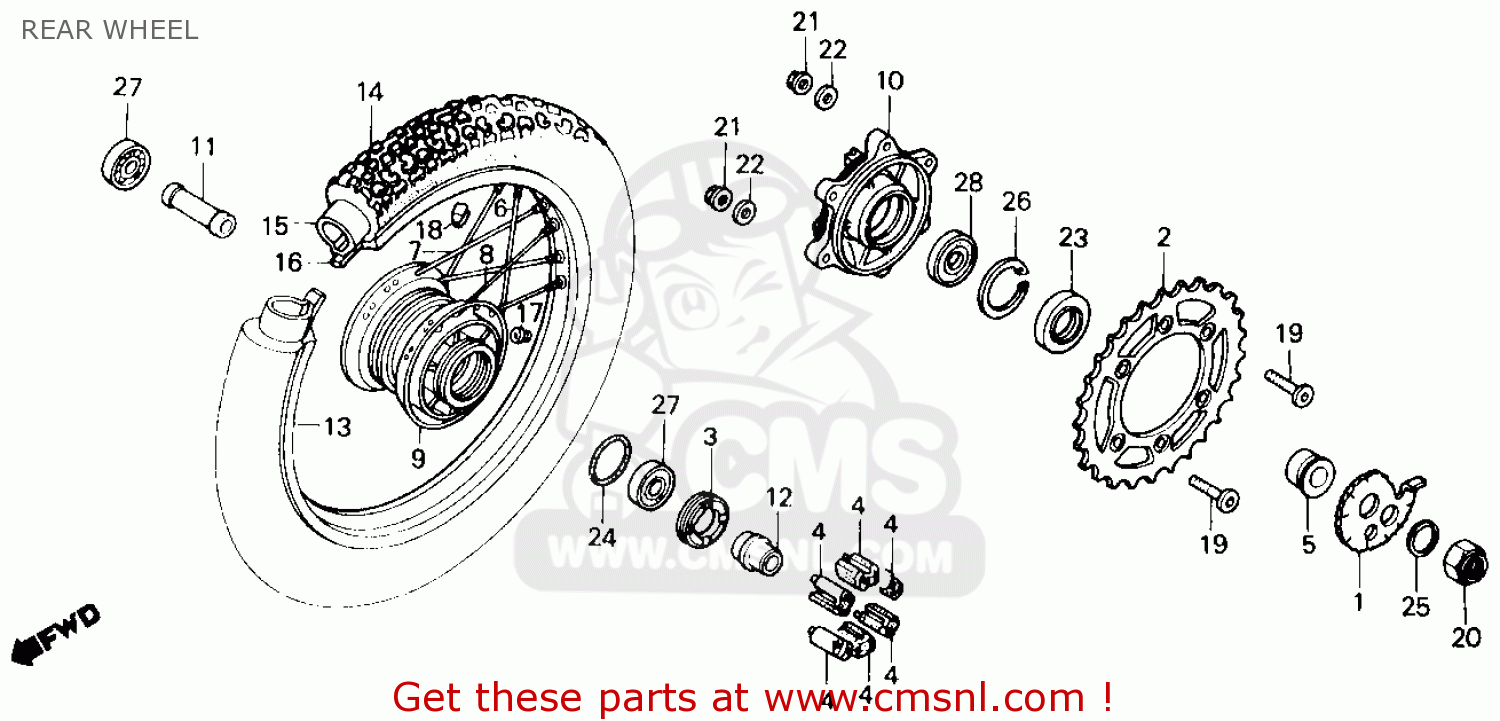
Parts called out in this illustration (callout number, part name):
1	ADJUSTER,L.CHAIN
2	SPR FINAL DRIVEN
3	RETAINER,RR.WHEEL
4	RUB,RR.WHEEL DAMP
5	COLLAR,RR.WHEEL
6	SPOK SET,B9X160.5
7	SPOK SET,B9X153.5
8	SPOKESET B9X157.5
9	HUB RR.WHEEL
10	FLANG FINAL DRIVE
11	COLLAR A,RR.AXLE
12	COLLAR B,RR.DIST.
13	RIM,RR.WHEEL
14	TIRE,RR. (BS)
15	TUBE,TIRE
16	FLAP,TIRE
17	CAP,RIM HOLE
18	BALANCER,HEEL(20G
19	BOLT,SPRKT FIXING
20	NUT,AXLE,16MM
21	NUT,FLANGE 8MM
22	WASHER,8MM
23	OIL,28X47.2X7
24	O-RING,54X2
25	SPG-WASHER 16MM
26	CIRCLIP IN 47MM
27	B/BRG RAD N/COM
28	B/BRG RAD N/COM
